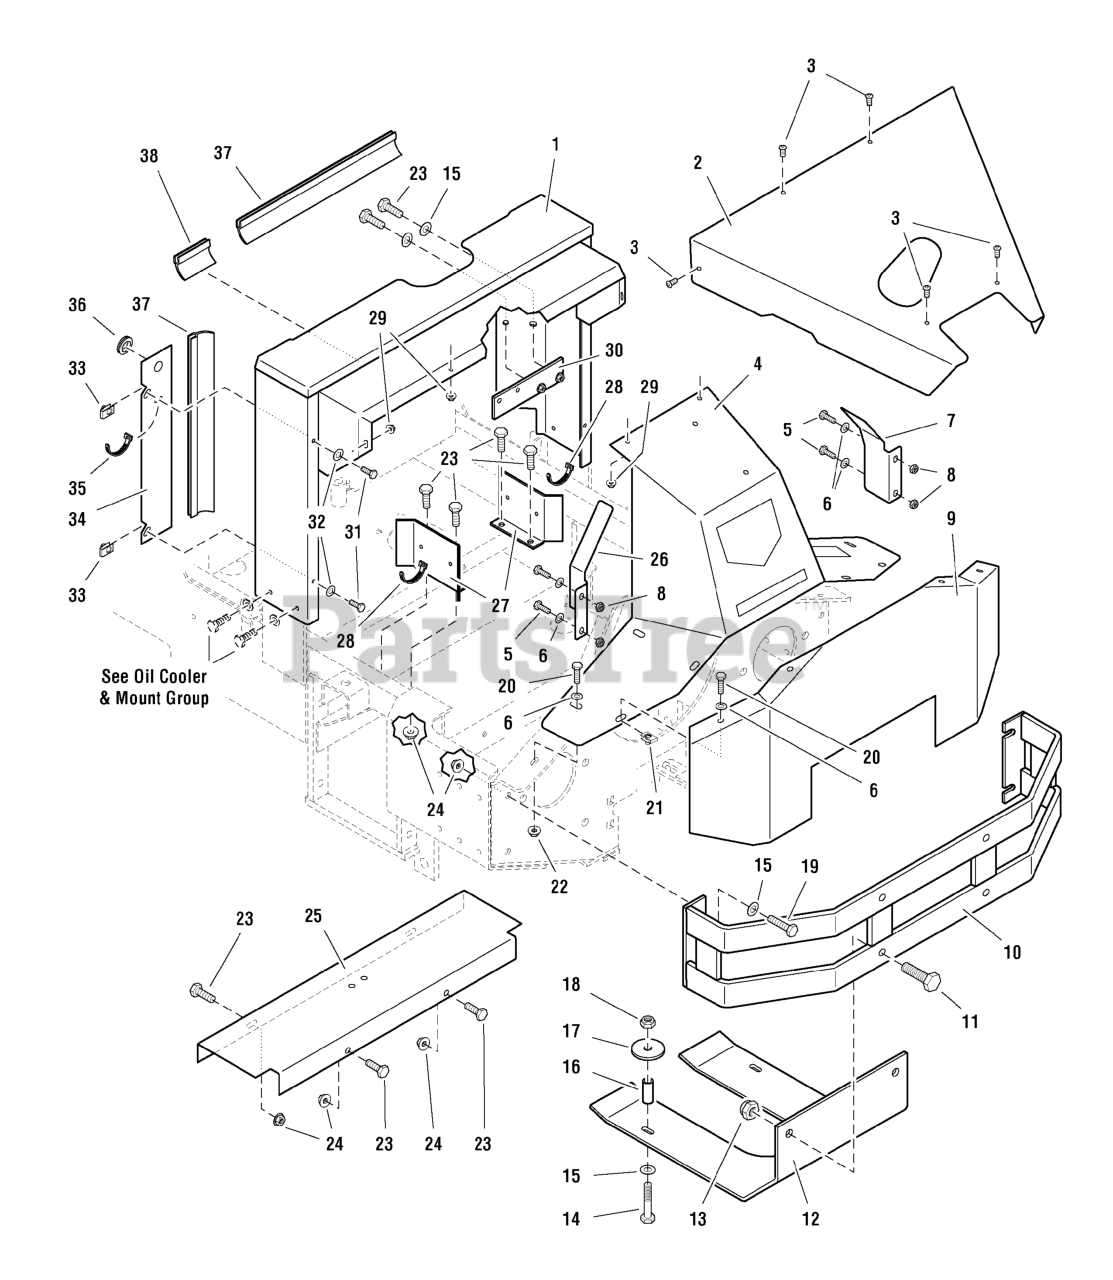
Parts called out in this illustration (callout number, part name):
1	RADIATOR SHROUD
4	REAR HOOD SUPPORT
5	BOLT, 5/16-18 X 3/4 GD5
6	WASHER, 5/16" SAE
7	FLYWHEEL GUARD-RH
8	NUT, 5/16-18 Hex Nylon Lock
9	REAR SHIELD
11	BOLT, 1/2-20 X 1-1/2, GD5 CZ
12	SKID SHIELD
13	NUT, Hex, Nylon Lock, 1/2-20
14	BOLT, 3/8-16 X 2-1/2" GD5 CZ
15	WASHER, 3/8 SAE
16	SPACER, .38 x .50 x 1.56
17	WASHER, 3/8 x 1-3/4
18	NUT, 3/8-16 HEX NYLON LOCK
19	BOLT, 3/8-16 X 1-1/4" GD5 CZ
20	BOLT, 5/16-18 X 1 GD5 YZ
21	BODY CLIP, 5/16-18-7GA MATERIAL
22	NUT, 5/16-18 HEX SERRATED FLANGE (SMALL)
23	BOLT, 3/8-16 X 1" GD5 CZ
24	NUT, 3/8-16 Hex Serrated Flange
25	DEBRIS SHIELD
26	FLYWHEEL GUARD-LH
27	SUPPORT PLATE
28	TIE WRAP, 11"
29	NUT, 1/4-20 Hex Nylock Flange
30	MOUNT, Water Separator
31	BOLT, 1/4-20 x 3/4
32	WASHER, 1/4 SAE
33	BODY CLIP, 1/4-20
34	SIDE BAFFLE
35	TIE WRAP, 5-1/2"
36	GROMMET, 1/2"
37	WIPER SEAL, 17"
38	WIPER SEAL, 3"
